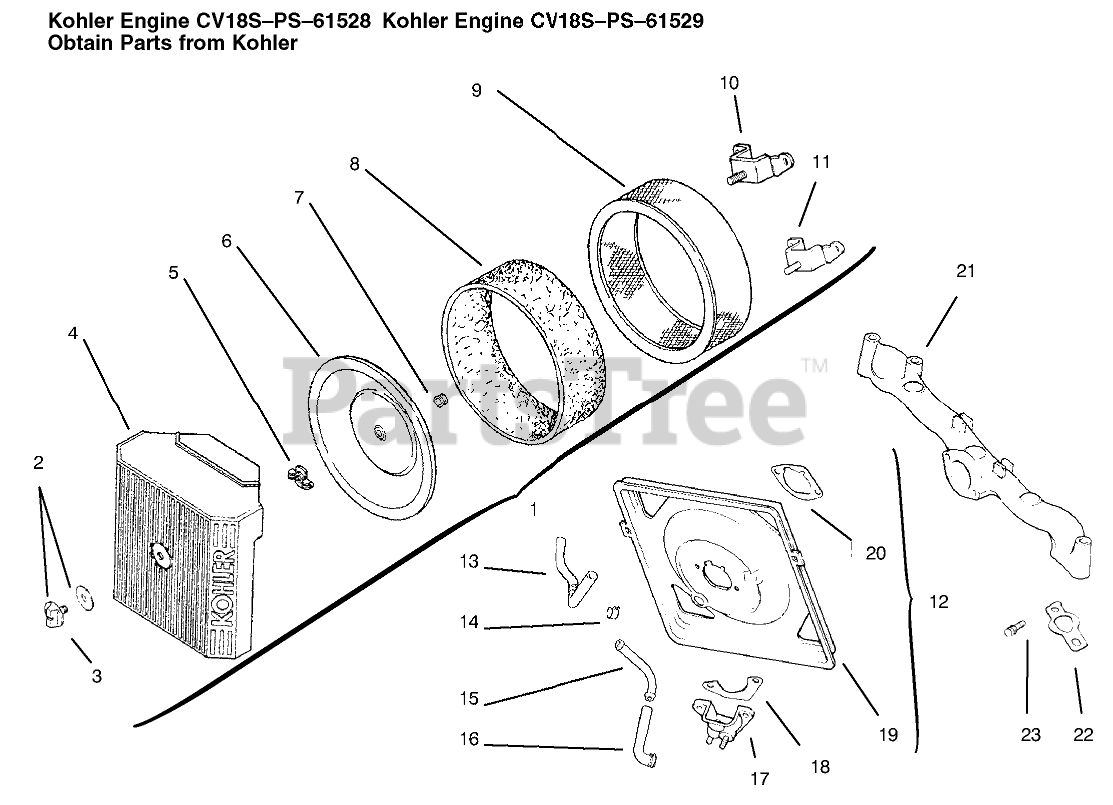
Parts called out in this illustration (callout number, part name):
1	Kit-Air Cleaner Cover
2	Kit-Knob w/Gasket
3	Knob-Cover
4	Cover-Air Cleaner
5	Wingnut
6	Cover-Inner AirCleaner
7	Seal, insert
8	Bement-Precleaner
9	Bement-Air Cleaner
10	Bracket-Air Cleaner
11	Bracket-Air Cleaner
12	Kit-Air Cleaner Base
13	Hose-Breather
14	Clamp
15	Fitting
16	Hose-Breather
17	Cup-Fuel Spitback
18	Gasket-Fuel Spitback
19	Base-Air Cleaner
20	Gasket-A/C Base
21	Manifold-Intake
22	Gasket-Intake, Manifold
23	Screw
